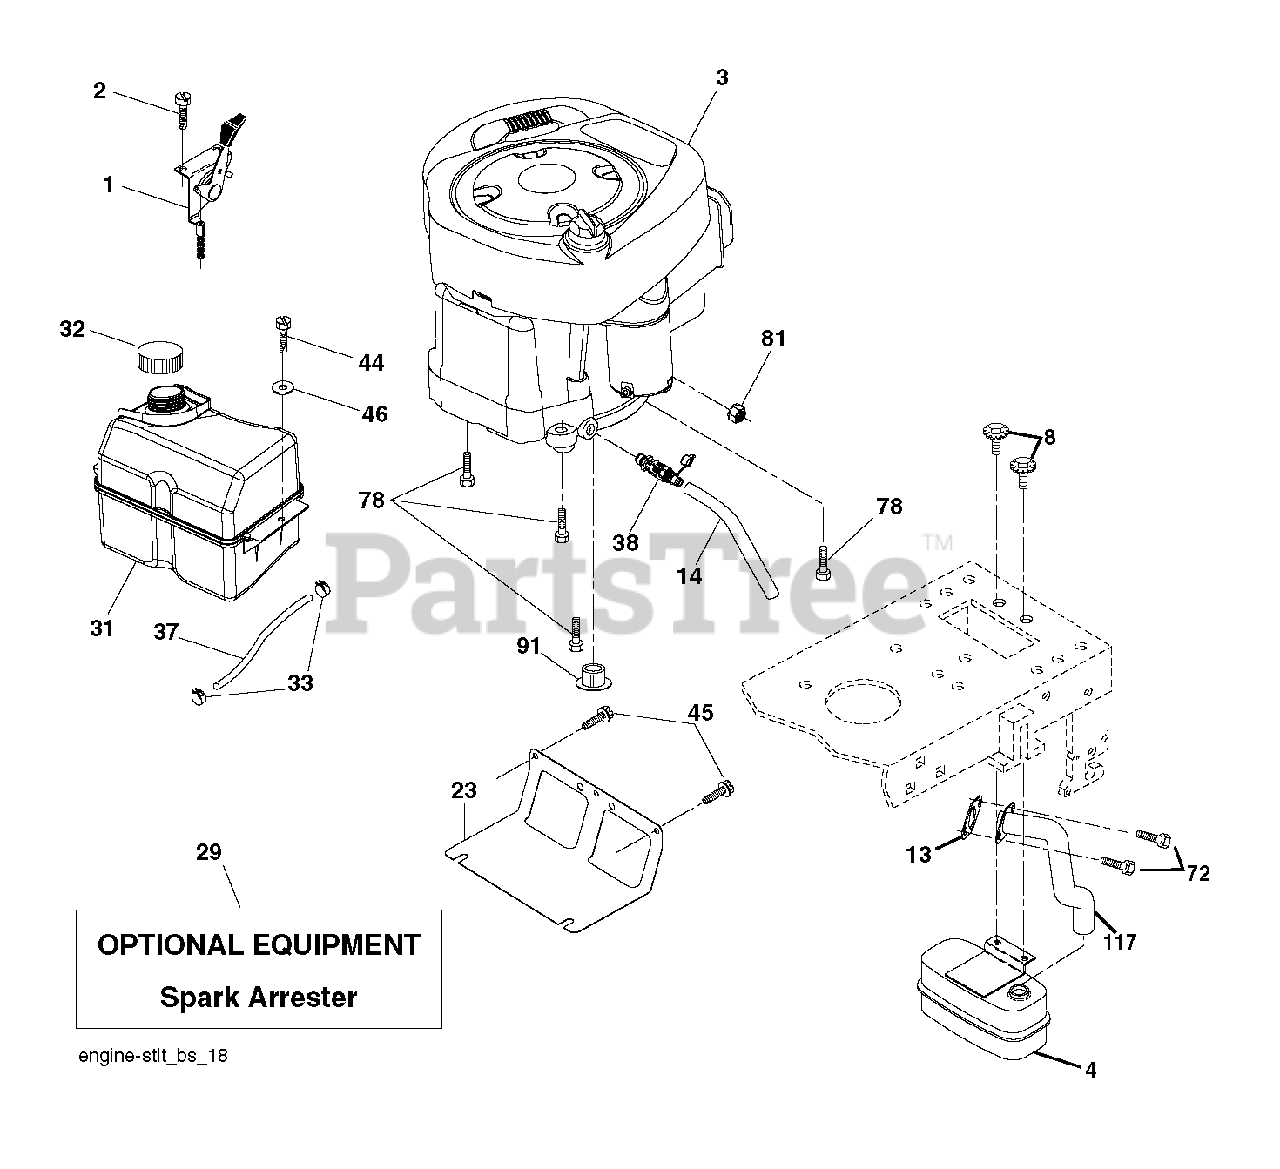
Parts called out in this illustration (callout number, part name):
1	CONTROL.TH/CK.C.
2	SCREW.#10 X 0.750.BOS
4	MUFFLER.SINGLE.CYL.KOHL/B&S
8	BOLT, 5/16-18 X 1 3/4
13	REPL BY 532 27 22-93
14	TUBE, DRAIN OIL ASM.
23	SHIELD.BROWNING.DBR.GUARD
29	KIT.SPARK ARRESTOR 794945 B&S
31	RP TANK FUEL FRT 1.5 GAL
32	CAP ASM.FUEL.2.25"FR.
33	HOSE CLAMP
37	LINE.FUEL.20
38	VALUE.OIL.DRAIN
44	SCREW HEXWSHR 1/4-20X3/4
45	SCREW, 3/8-16X3/4
72	SCREW.SOCKET HD.5/16-1
78	SCREW.3/8-16
81	NUT
91	BUSHING.1.375OD
117	EXHAUST.TUBE.B&S.
